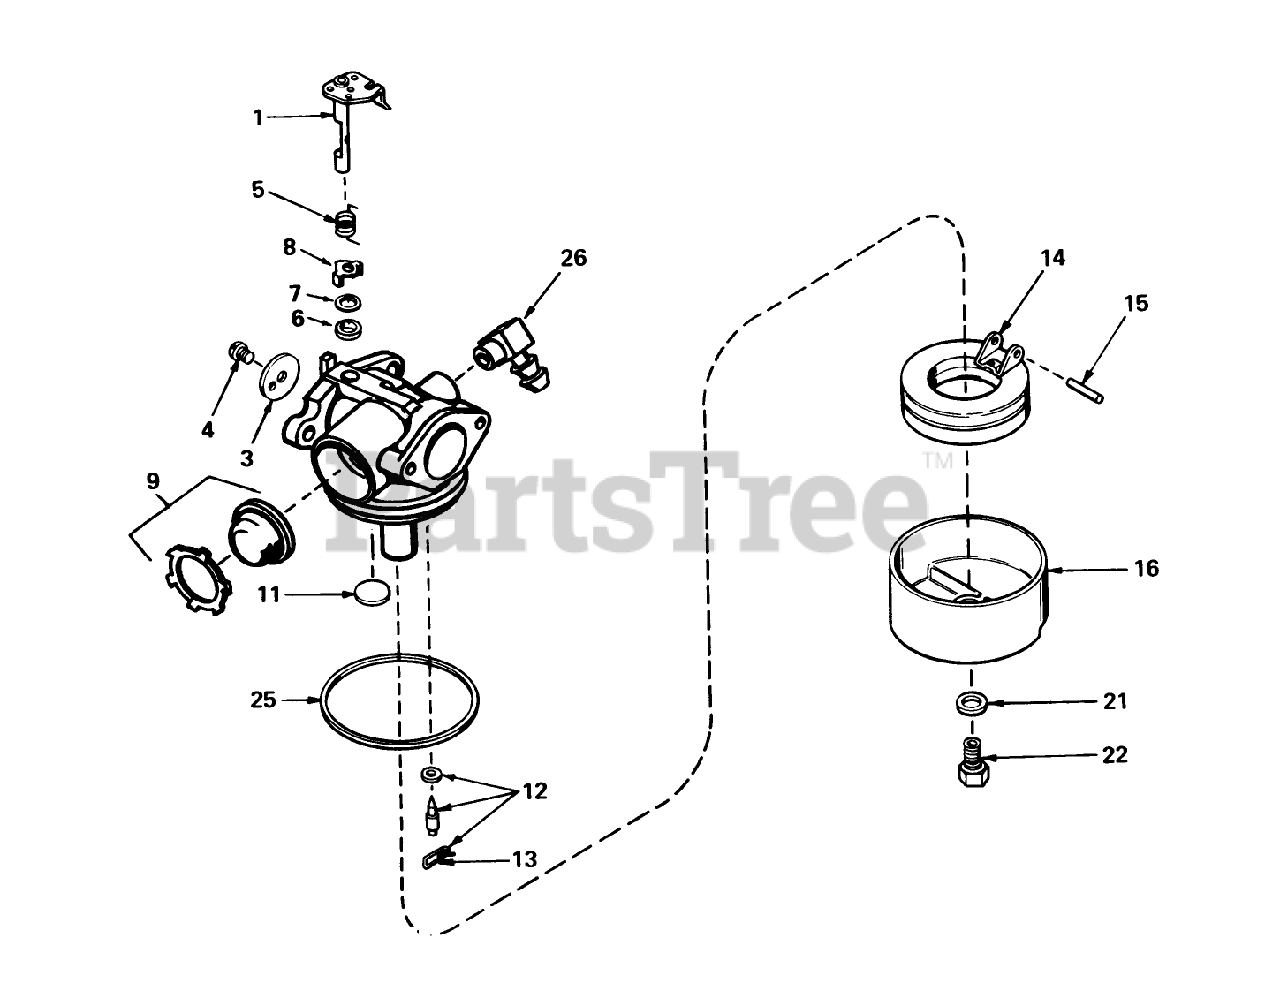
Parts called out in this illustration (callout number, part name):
1	Throttle Shaft and Lever ASM
3	Throttle-Shutter
4	Screw-Shutter
5	Spring, Return
6	Seal-Dust
7	Washer-Seal, Dust
8	Retainer, Seal
9	Primer Assy.
11	Plug-Welch, Atmospheric Vent
12	Inlet Needle, Seat Clip Assy. (Incl. No. 13)
13	Clip-Spring
14	Float
15	Shaft-Float
16	Bowl Float
21	Gasket-Bowl
22	Nut-Float Bowl
25	O Ring-Bowl, Float
26	Fitting-Fuel
